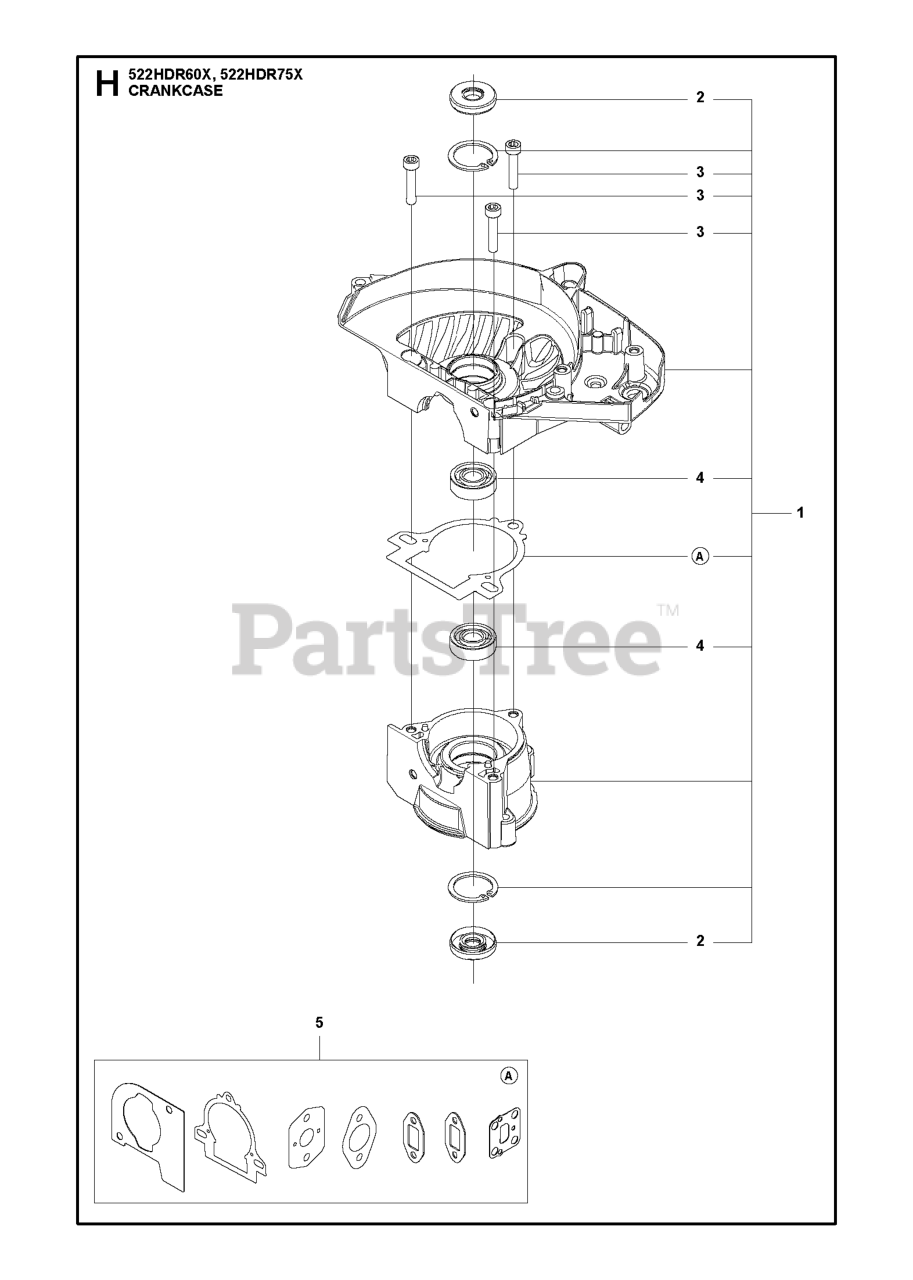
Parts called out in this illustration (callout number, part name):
1	CRANKCASE ASSY KIT 522
2	SEALING RING
4	BALL BEARING
5	GASKET KIT 522
